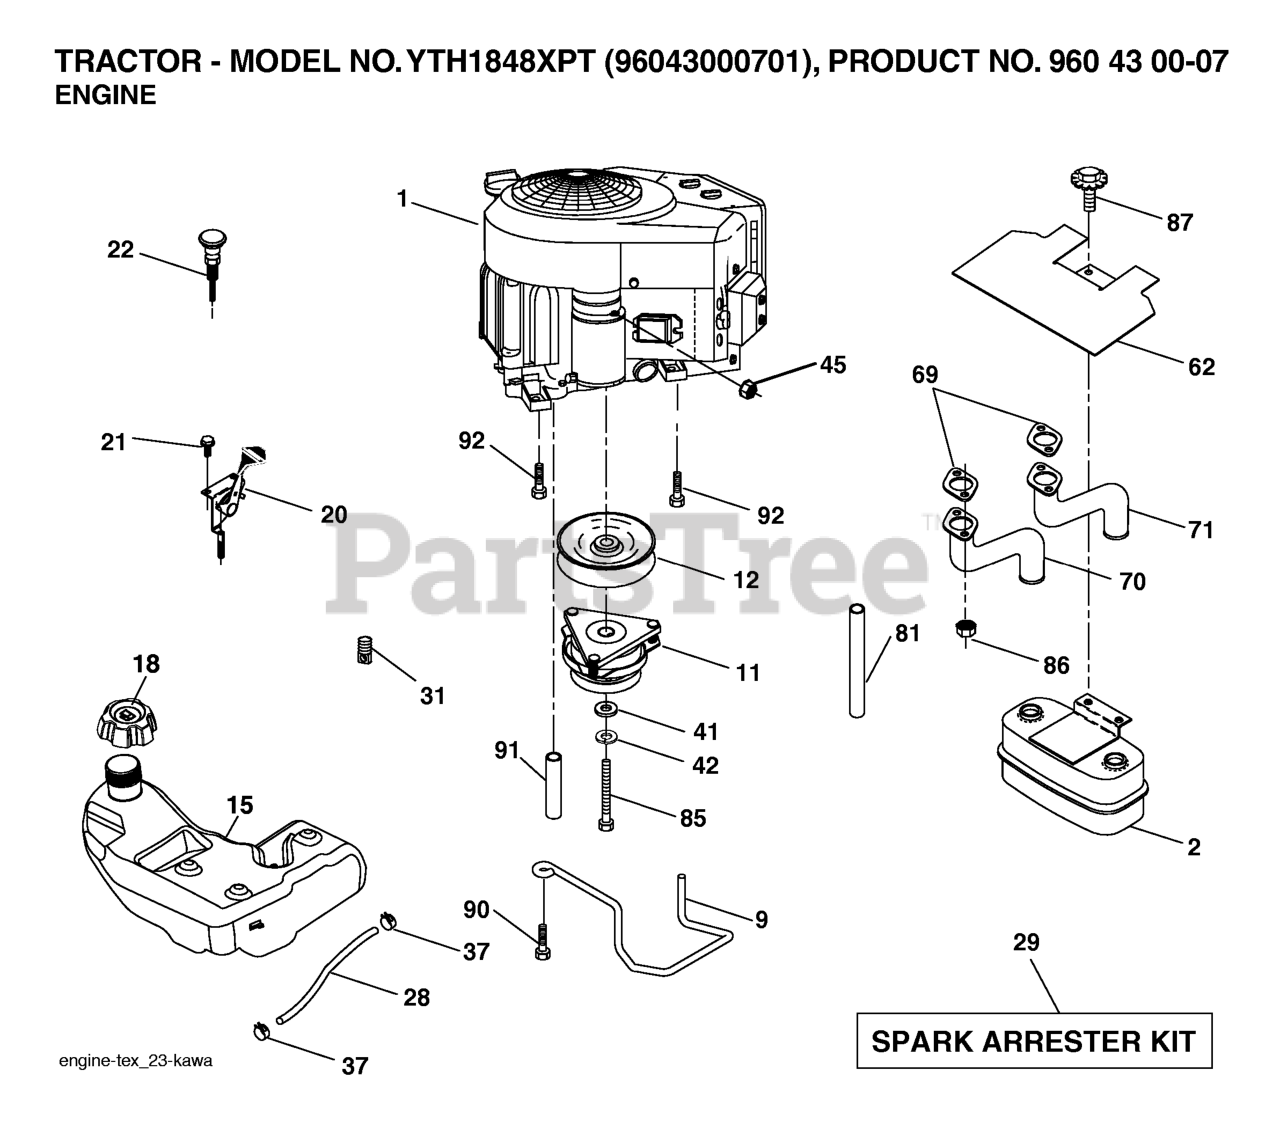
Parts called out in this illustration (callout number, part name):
2	MUFFLER.TWIN.CYL.LOW.TONE
9	KEEPER.BELT.ENGINE.4.2
11	CLUTCH MZ ZTR GT.48/54"1.125"
12	PULLEY ENGINE
15	TANK.FUEL.4GAL
18	CAP.FUEL.TANK.3"GREY
20	THROTTLE CONTROL
21	SCREW
22	CONTROL, CHOKE
29	KIT.SPARK ARRESTOR 794945 B&S
37	HOSE CLAMP
42	LOCKWASHER
45	NUT
62	RP SHIELD HEAT MUFFLER
70	EXHAUST.TUBE.LH.KAWASAKI.
71	EXHAUST.TUBE.RH.KAWASAKI.
81	TUBE, DRAIN OIL ASM.
85	BOLT HEX 7/16-20 X 3.75 GR. 5
86	NUT.HEX.FLANGE.TOPLOCK
87	BOLT.5/16-18UNCX1.W/SEMS.BLK
90	SCREW 3/8-16X1
91	BUSHING.1.375OD
92	SCREW 3/8-16X1
